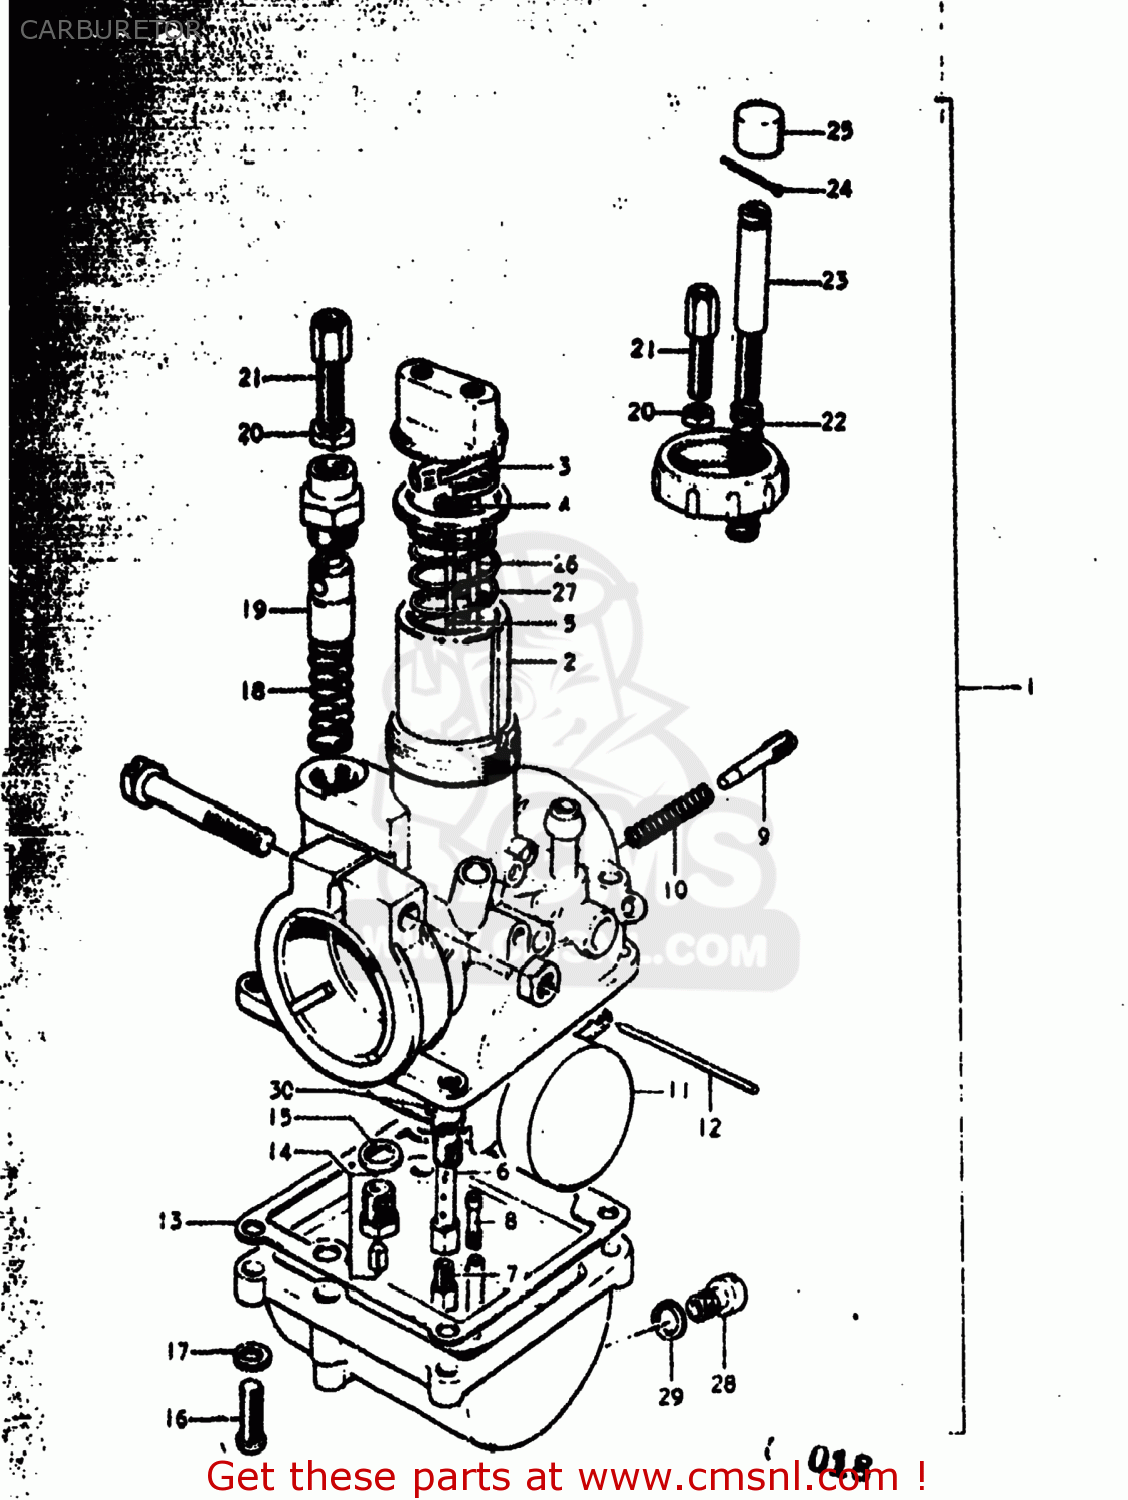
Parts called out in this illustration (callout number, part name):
1	CARBURETOR ASSEMBLY
2	VALVE,THROTTLE
3	STOPPER,NEEDLE CLIP
4	CLIP,NEEDLE
5	NEEDLE JET
6	JET,NEEDLE
7	JET
8	JET
9	SCREW,PILOT AIR
10	SPRING
11	FLOAT
12	PIN,FLOAT
13	GASKET,FLOAT CHAMBER (NAS)
14	VALVE ASSEMBLY,NEEDLE
15	GASKET,NEEDLE VALVE (NAS)
16	SCREW
17	LOCK WASHER
18	SPRING
19	PLUNGER,STARTER
20	NUT
21	ADJUSTER,CABLE
22	SPRING,THROTTLE SCREW
23	SCREW,THROTTLE STOP
24	PIN 12X10
25	CAP,THROTTLE VALVE STOP SCREW
26	ROD,THROTTLE VALVE ADJUST
27	SPRING,THROTTLE VALVE
28	PLUG
29	GASKET,DRAIN,PLUG (NAS)
30	PLATE
